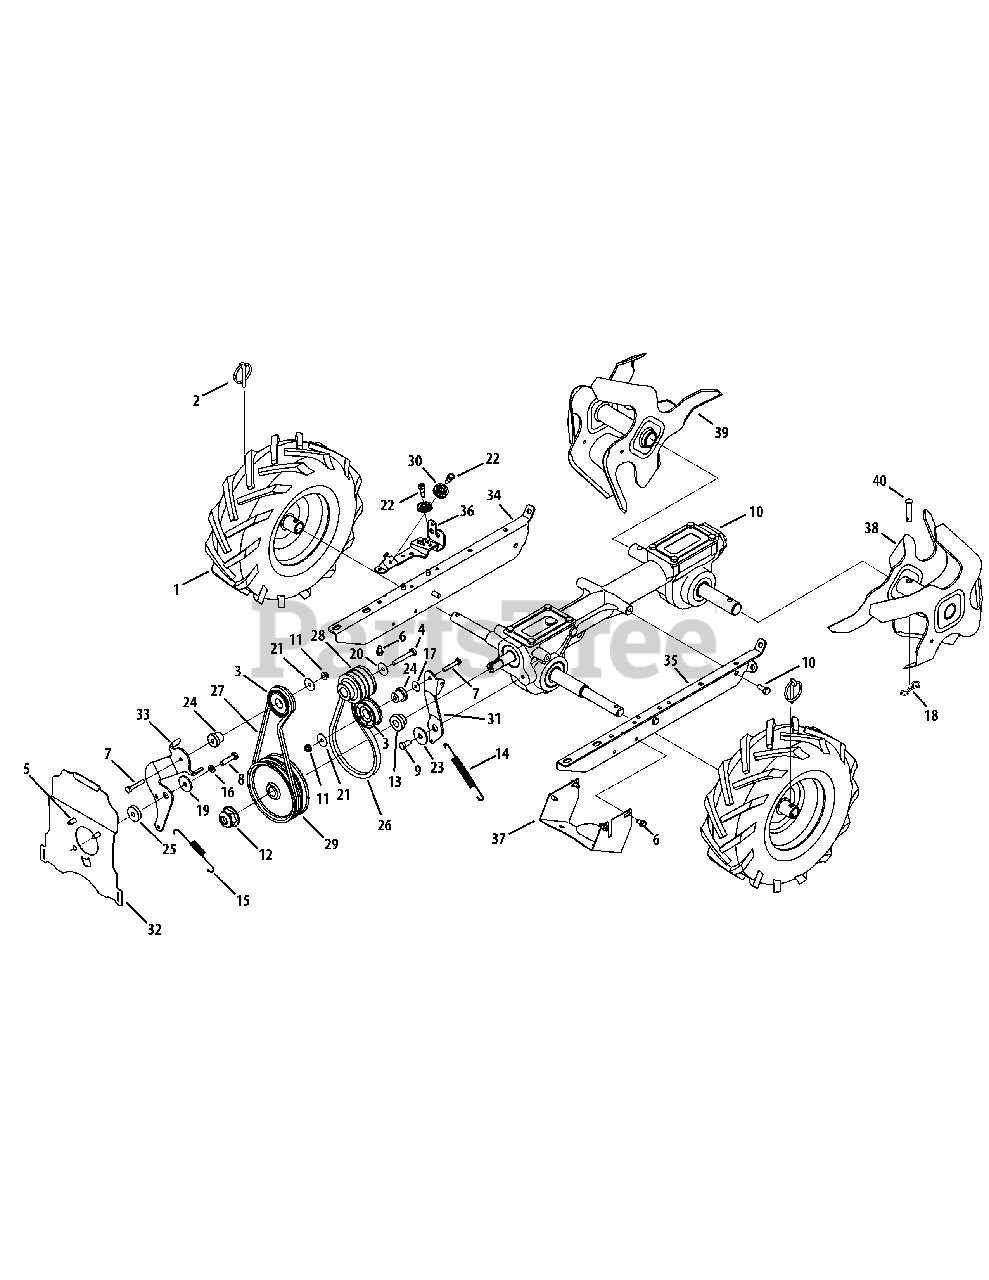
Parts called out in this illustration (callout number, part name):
1	Complete Wheel. Assy., 13 x 5 x 6
2	Click Pin
3	Idler Pulley Assembly
4	Hex Screw, 3/8-24 x 2.00
5	Hex Screw, 5/16-24 x .625
6	Self Tapping Screw, 1/4-20 x .500
7	Hex Screw, 1/4-20 x 1.50
8	Hex Screw, 5/16-18 x 1.25
9	Hex Screw, 5/16-18 x .75, Patch
10	Transmission Assembly
11	Hex Lock Nut, 1/4-20
12	Nut, 9/16-18, Flange Lock
13	Hub, 5/8 Spline
14	Extension Spring, .480 OD X 5.00 LG
15	Extension Spring, PTO
16	Lock Washer, 5/16
17	Washer, .28 x .74 x .063
18	Internal Cotter Pin
19	Flat Washer, .330 X 1.25 X .120
20	Bell Washer, .396 x 1.140 x .095
21	Flat Washer, .265 x 1.0 x .030
22	Shoulder Screw, .342 x .335 1/4-28
23	Pivot Idler Spacer
24	Shoulder Spacer, .260 x .785 x .538
25	Pivot Idler Spacer
26	V-Belt
27	V-Belt
28	Engine Pulley
29	Transmission Pulley
30	Cable Roller
31	Idler Bracket, Forward
32	Cover Plate
33	Idler Bracket, Reverse
34	Mounting Frame, RH
35	Mounting Frame, LH
36	Pulley Bracket
37	Pulley Shield
38	Tine Assembly, LH
39	Tine Assembly, RH
40	Clevis Pin, .375 x 1.75
